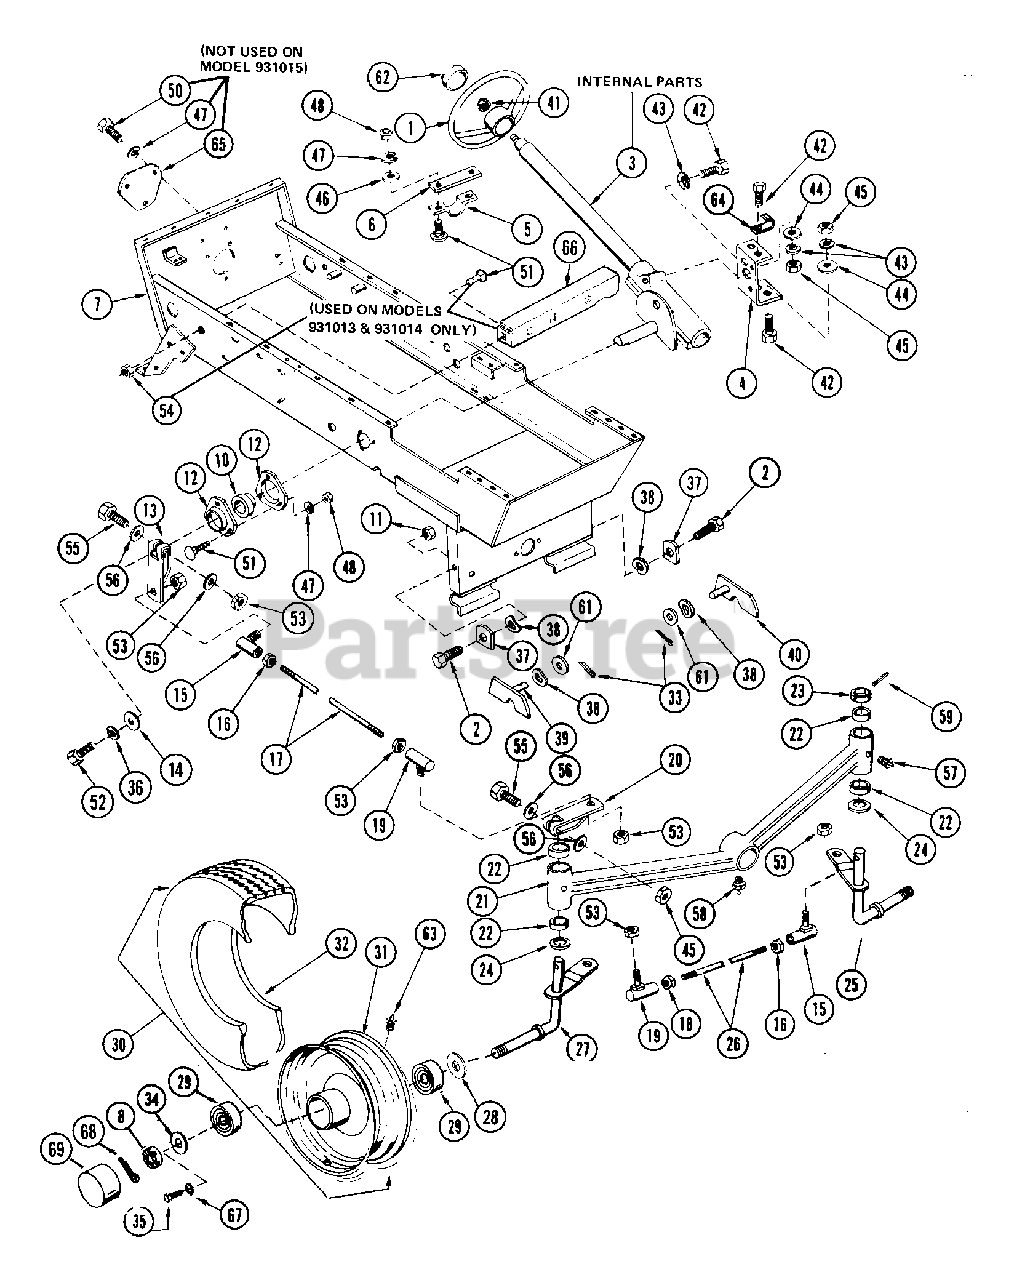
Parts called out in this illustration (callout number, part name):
1	STEERING WHEEL
2	BLT-HEX .38-16X1.00 PL
3	STEERING GEAR ASSEMBLY
3	STEERING GEAR
4	MOUNTING BRACKET
5	STEERING COLUMN CLAMP
7	MAIN FRAME ASSEMBLY
7	FRAME ASSEMBLY SERVICE 12 HP
7	FRAME ASSEMBLY SERVICE 14 AND
8	NUT-SL 1.0-14
10	BRG-BALL 1.0X2.047X1.20
11	NUT-LK .375-16 PL
12	BEARING FLANGE
13	STEERING ARM
14	WSHR-FL-STL .563X2.000X.135 PL
15	BALL JOINT L.H.
16	NUT-JAM .50-20 LH THD PL
17	DRAG LINK
18	NUT-JAM .50-20 PL
19	BALL JOINT R.H.
20	STEERING ARM
21	FRT AXLE
22	BSHG-SLV 1.000X1.125X.875
23	SPINDLE COLLAR L.H.
24	PLASTIC WASHER
25	LH SPINDLE
25	L.H. SPINDLE
26	TIE ROD
27	RH SPINDLE
27	R.H. SPINDLE
28	WSHR-FL-STL 1.015X1.500X.125
29	BRG-BALL 1.0X2.0X.55
30	FRONT TIRE ASSEMBLY 16 X 6.50
32	TIRE
33	PIN-COTR .12X.75 PL
34	SPINDLE WASHER
35	BLT-HEX .38-16X.75 PL GR5
36	WSHR-LK .500X.151 HVY PL
37	LOCK STOP
38	SPRING WASHER
39	LATCH R. H.
40	LATCH L. H.
41	NUT-LK-JAM .625-18 YWZC
42	BLT-HEX .38-16X1.00 PL GR5
43	WSHR-LK .375X.094 MED PL
44	WSHR-FL-STL .438X1.0X.083 PL
45	NUT-LK TOP .375-16 GR C YWZC
46	WSHR-FL-STL .38X.875X.083 PL
47	WSHR-LK .312X.097 PL HVY
48	NUT-HEX .312-18
50	BLT-HEX .31-18X.75 PL GR2
51	BLT-RDHDSQNK .31-18X1.00 PL
52	BLT-HEX .50-13X1.25 PL GR5
53	NUT-LK-CROWN .50-13 GR C PL
54	NUT-LK .312-18 GR A PL
55	BLT-HEX .50-13X2.50 PL GR5
56	WSHR-FL-STL .505X.875X.024 PL
57	SPIN DRIVE ZERK FITTING
58	ZERK FITTING
59	PIN-ROLL .250X1.75
60	PIN-ROLL .250X1.50
61	WSHR-FL-STL.406X.812X.065PL
62	STEERING WHEEL CAP
63	ZERK FITTING
64	J-CLAMP
66	BRACE
67	WSHR-LK-EXT .375X.050
68	PIN-COTR .18X1.25 PL
69	FRONT HUB CAP
